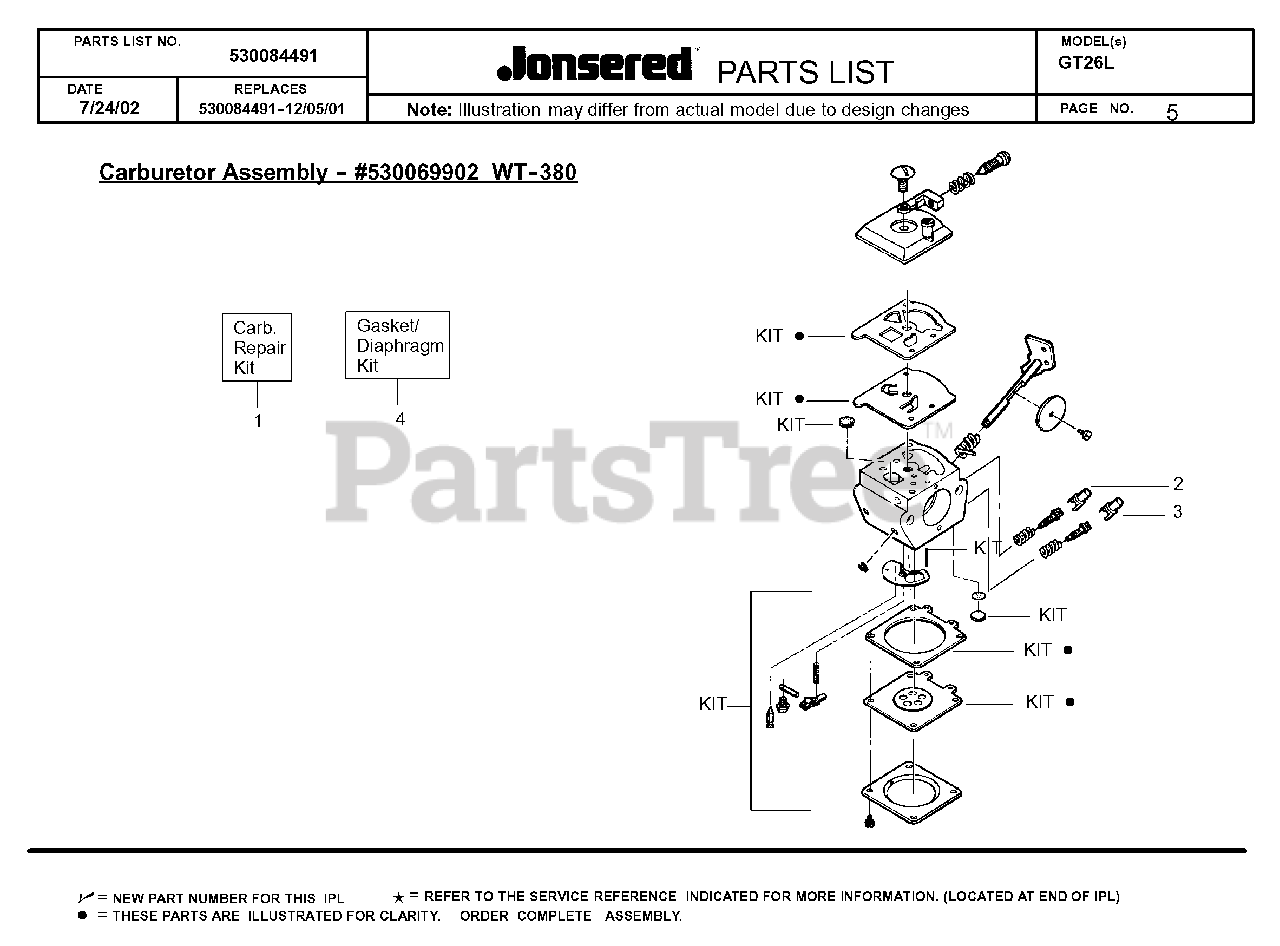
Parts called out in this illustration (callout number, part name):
1	CARB REPAIR KIT
2	LIMITER CAP-LOW
3	LIMITER CAP-HIGH
4	GASKET/DIAPHRAGM KIT
